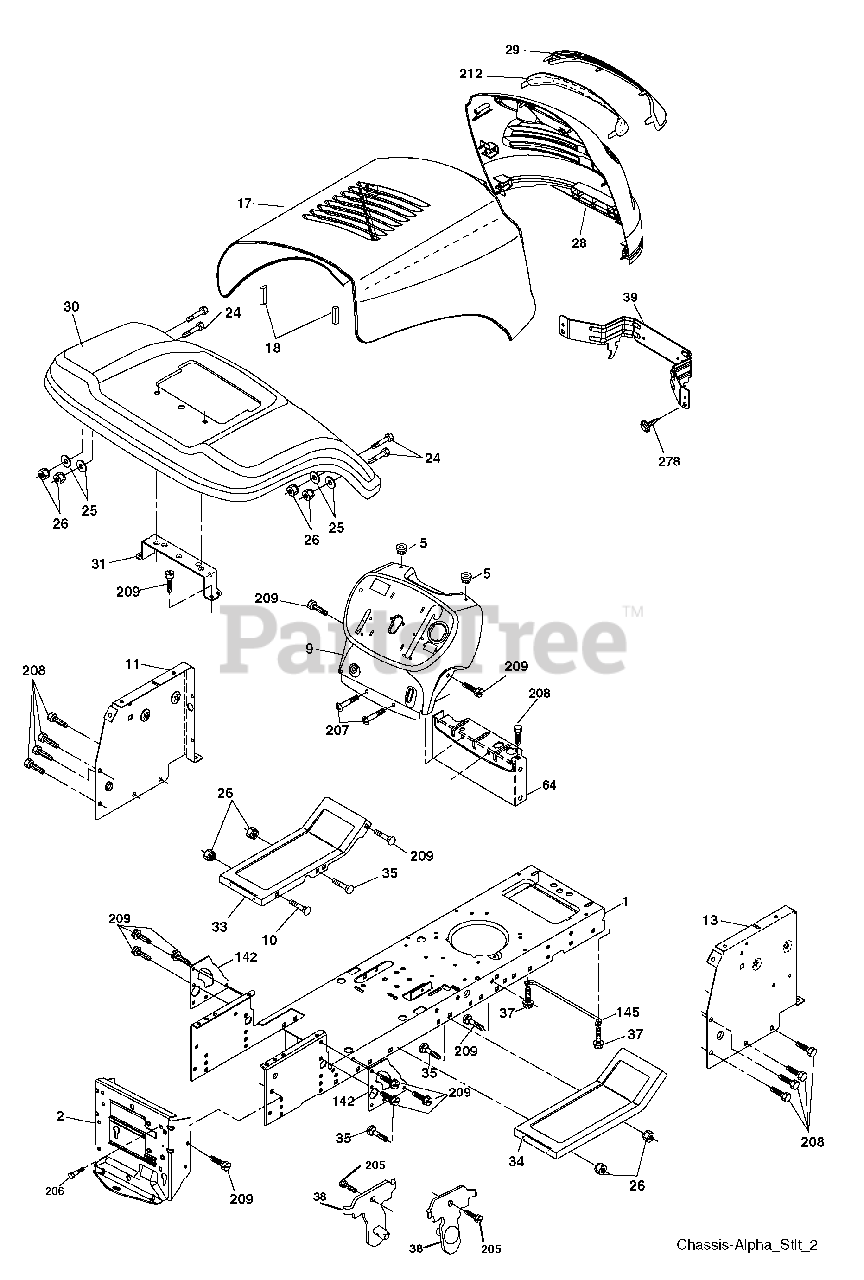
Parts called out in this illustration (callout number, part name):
1	Chassis
2	Drawbar, Stretch
5	Bumper, Hood/Dash
9	Dash
10	Bolt, Carriage 3/8-16 x 1
11	Panel Dash LH
13	Panel Slkscr Dash RH
17	Hood
18	Bumper Hood
24	Bolt Fin Hex 3/8-16 unc x 1 Gr. 5
25	Washer 13/32 x 13/16 x 12 Ga.
26	Nut Lock Hex w/Ins 3/8-16 unc
28	Grille/Lens Asm.
29	Lens Grille Bar
30	Fender
31	Bracket Fender Repl 109873X
33	Footrest Pnt LH
34	Footrest Pnt RH
35	Bolt Rdhd Sht Sqnk 3/8-16 x 3/4
37	Screw Thdrol 5/16-18 x 1/2 TYT
38	Bracket Asm. Pivot Mower
39	Bracket Pivot
64	Dash Lower
142	Plate Reinforcement
145	Rod Pivot Chassis/Hood
205	Screw Thdrol 3/8-16 x 1/2
206	Bolt Shoulder 5/16-18
207	Screw 5/16-18 x 1/2
208	Screw Thdrol 3/8-16 x 1/2
209	Screw Hex Wsh Thdrol 3/8-16
212	Insert Lens Reflect
278	Screw #10 x 0.750 BOS Thread
278	Plug Button Blk 359 Dia Choke
278	Plug Dome Plastic
